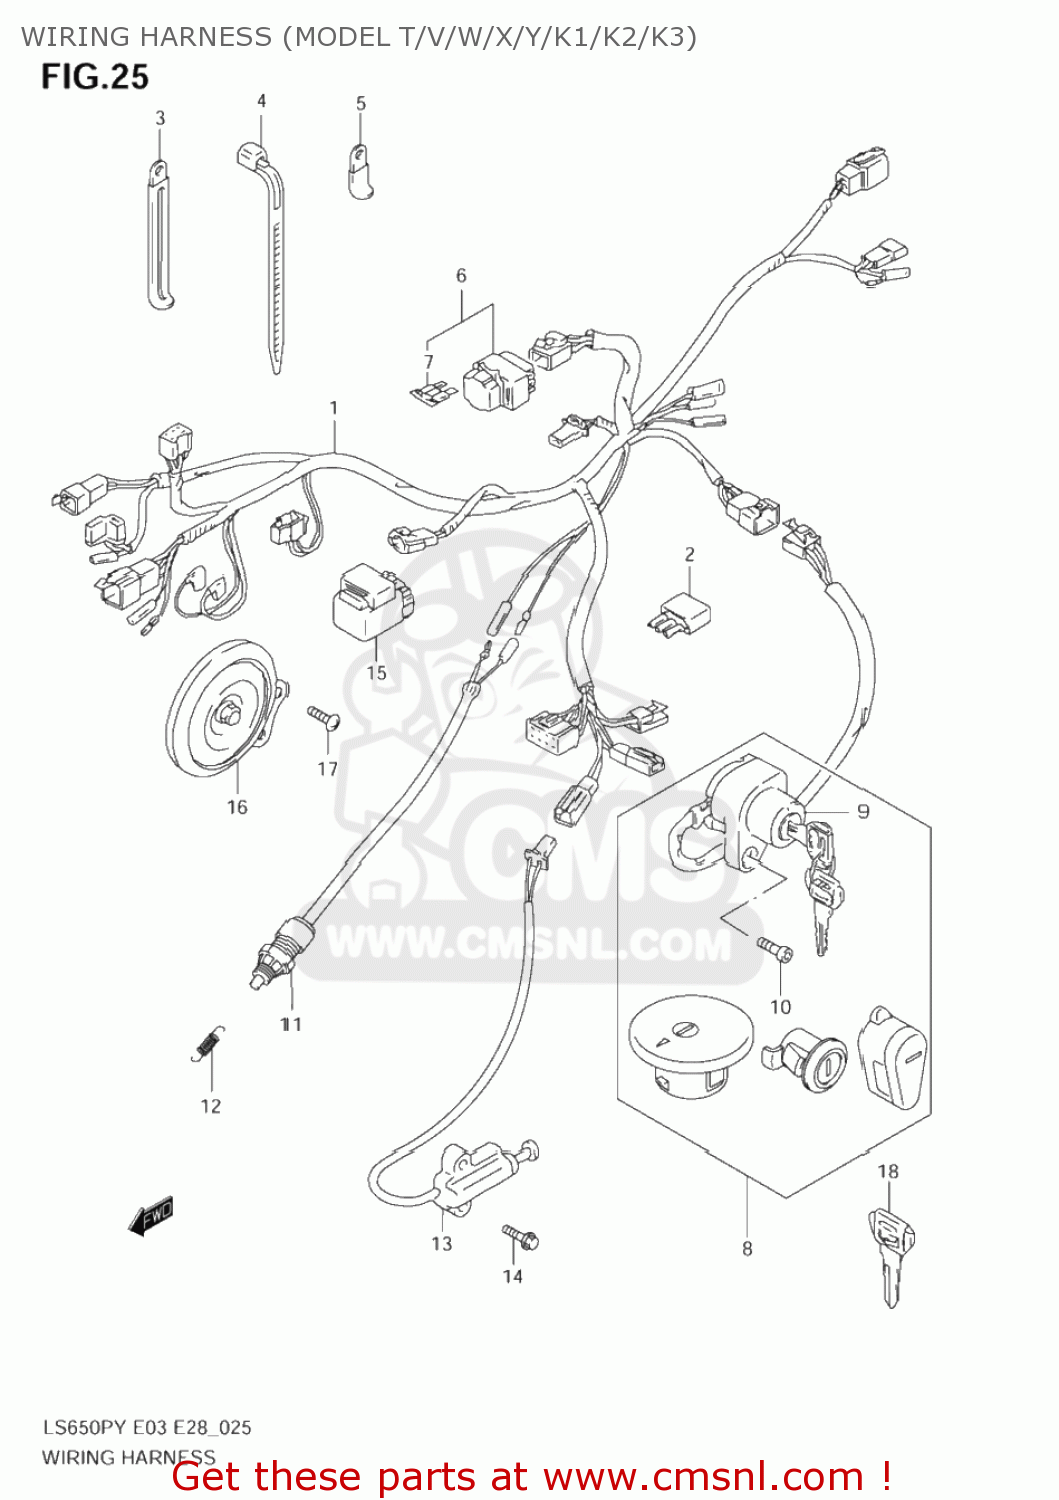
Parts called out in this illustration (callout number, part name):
1	HARNESS,WIRING
2	DIODE(STANLEY DE8804)
3	CLAMP(L:65)
4	CLAMP(L:125)
5	CLAMP
6	BOX ASSY,FUSE
7	FUSE(20A)
8	LOCK SET
9	SWITCH ASSY,IGNITION
10	BOLT
11	SWITCH ASSY,STOP LAMP
12	SPRING
13	SWITCH ASSY,SIDE STAND WARNING
14	BOLT
15	RELAY ASSY
16	HORN ASSY
17	SCREW 6X12
18	KEY,BLANK(TYPE:C)
